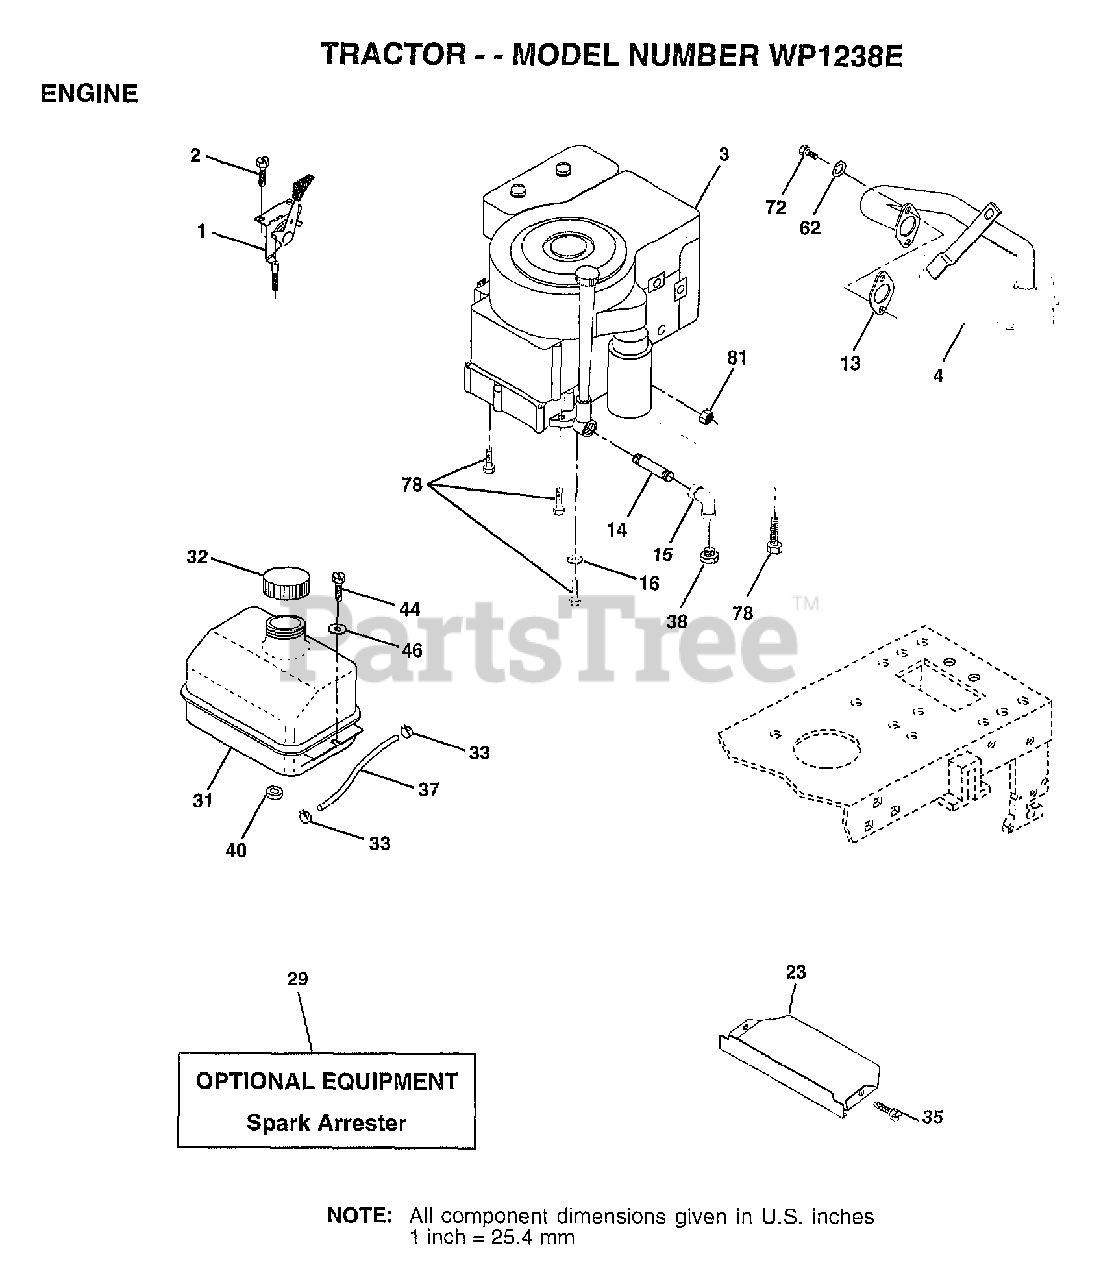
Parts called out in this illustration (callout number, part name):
1	THROTTLE CONTROL
2	SCREW LT
4	MUFFLER
13	GASKET ENG 1 313 LD TIN PLATED
14	PIPE NIPPLE
15	ELBOW
16	LOCKWASHER
23	SHIELD.BRN/DBR.GD
31	TANK.FUEL.LT.
32	CAP ASM FUEL
33	HOSE CLAMP
35	SCREW
37	LINE FUEL
44	SCREW HEX CRT
46	WASHER
62	LOCKWASHER
72	SCREW
78	SCREW
81	NUT
